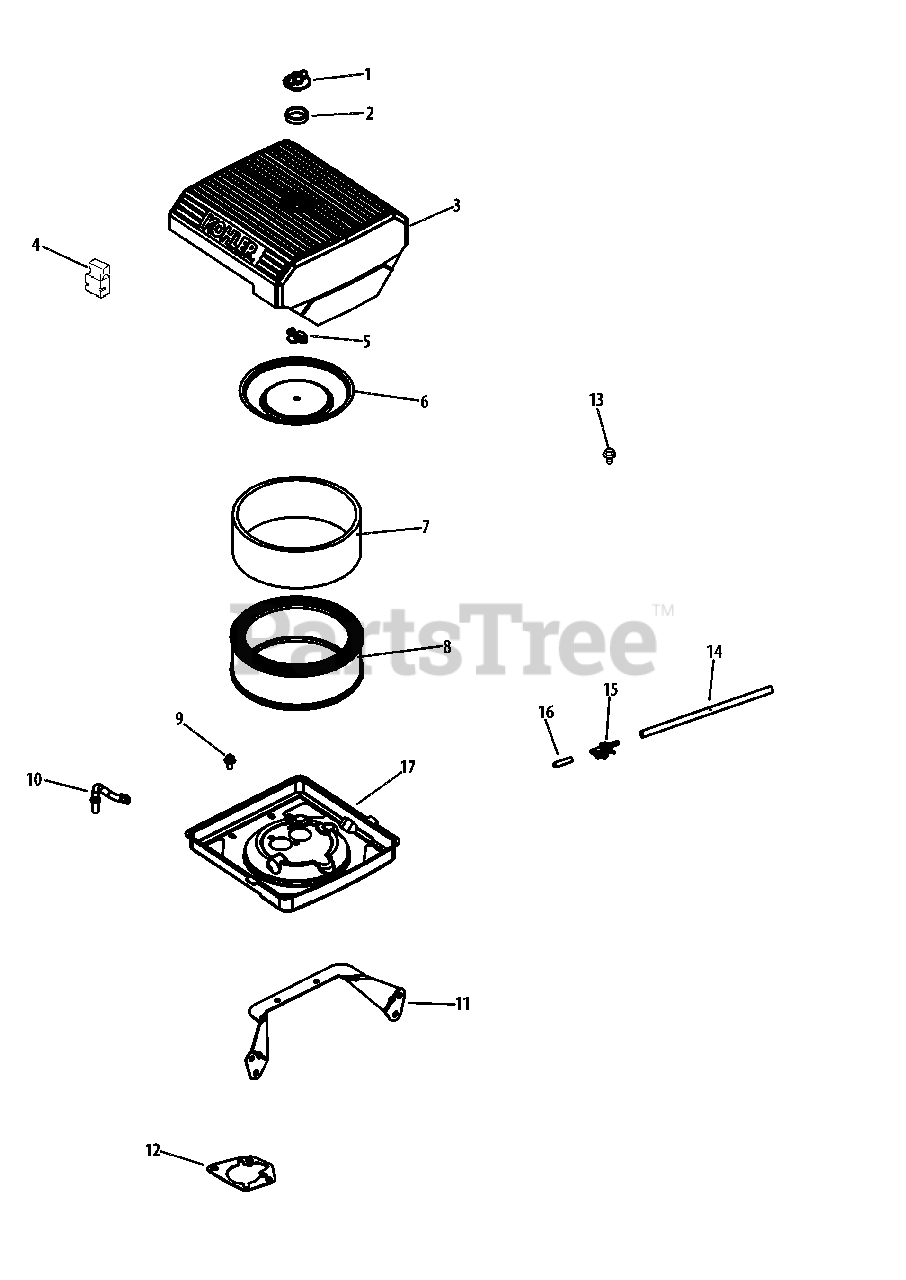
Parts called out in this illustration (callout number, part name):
4	Inner Air Cleaner Seal
6	Inner Air Cleaner Cover
7	Pre-cleaner Element (Low)
8	Air Filter & PreCleaner Elements
9	Evaporative Hose Connector
11	Air Cleaner Base Bracket
12	Air Cleaner Base Gasket
13	Thread Forming Screw
14	Evaporative Hose, 20"
15	Evaporative Connector
17	Air Cleaner Base Kit
